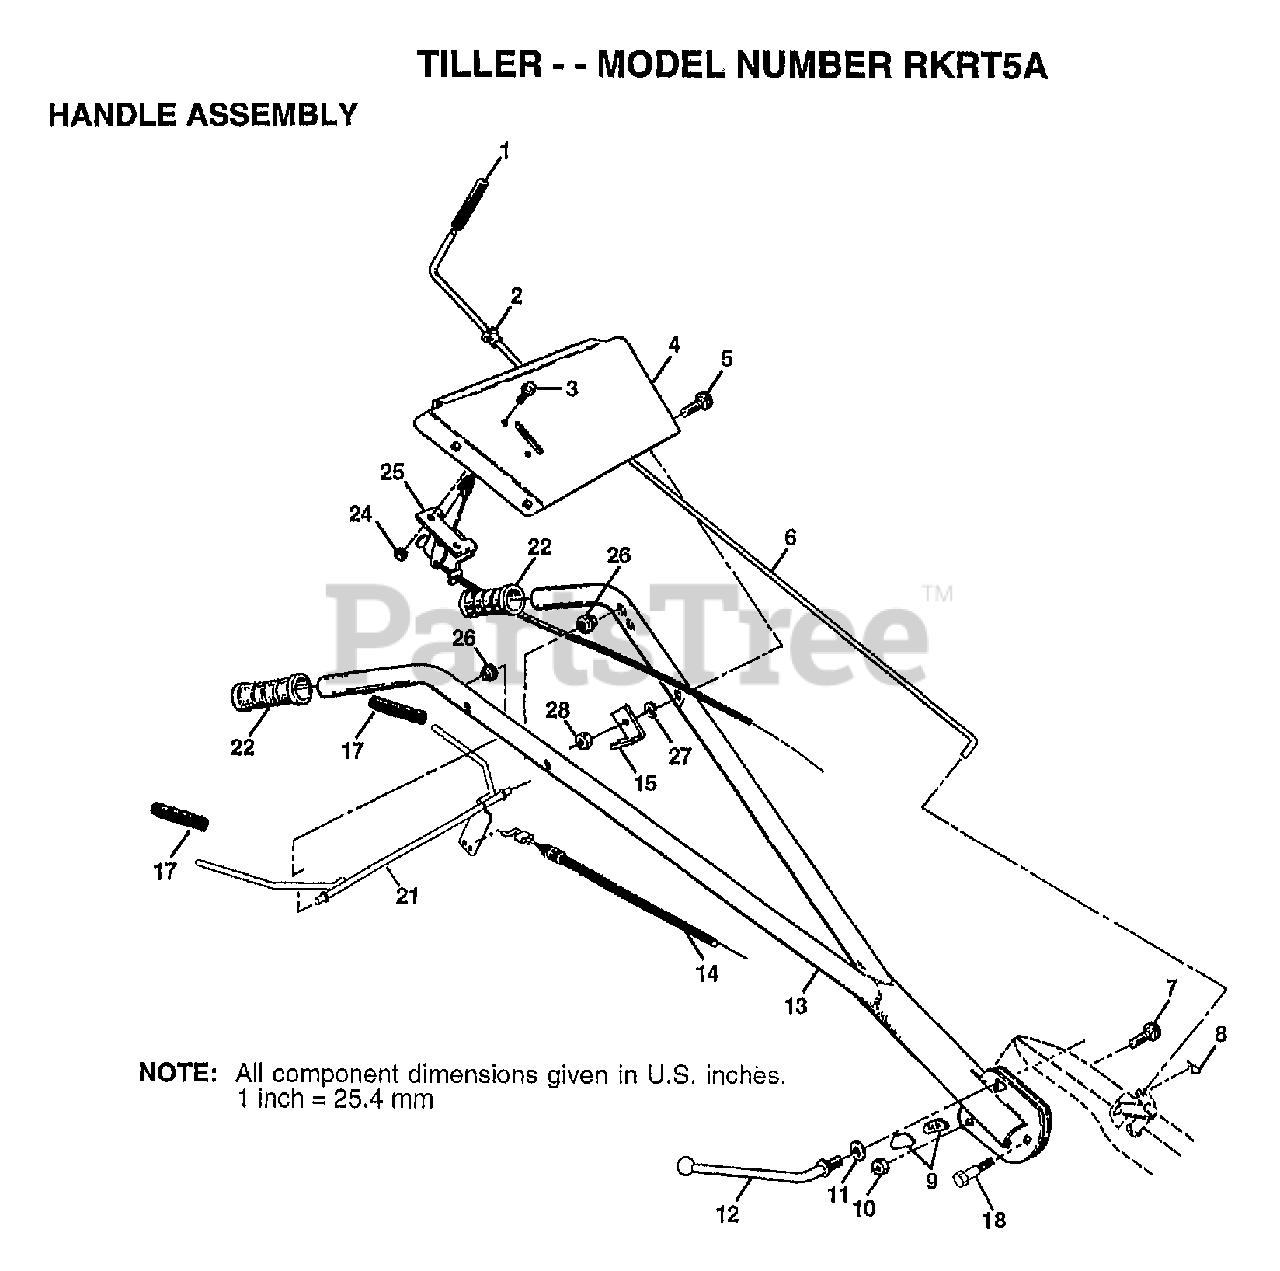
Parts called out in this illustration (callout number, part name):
1	GRIP TI
2	BUSHING
3	SCREW.PNHD.10-24
4	BRACKET, HANDLE
5	BOLT CARRIAGE CRT
6	ROD SHIFT CRT
7	BOLT D
8	RETAINER M
9	LOCK CRT
10	LOCKNUT
11	WASHER CRT
12	LEVER LOCK CRT
14	"CABLE, CLUTCH"
15	BRACKET.CLUTCH.CA
17	GRIP BAR CRT
18	BOLT PIVOT
21	BAR CONTROL
22	"GRIP,HANDLE"
25	"CONT,THROTTLE"
26	GROMMET.HANDLE.V-
27	LOCKWASHER
28	NUT
